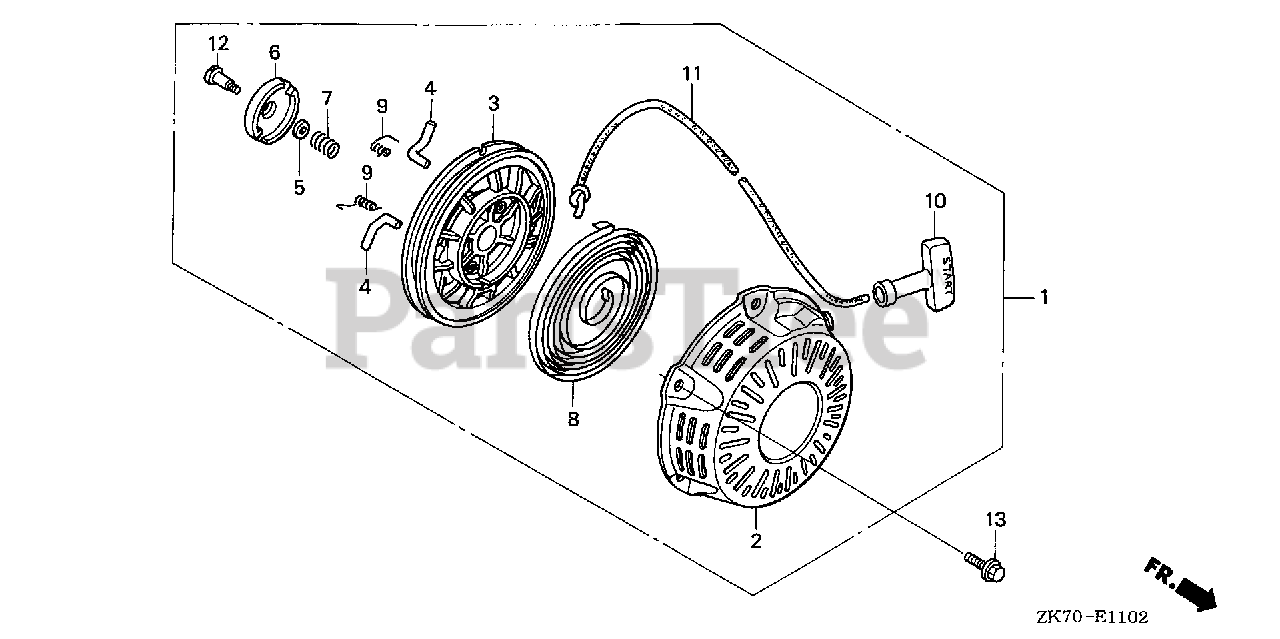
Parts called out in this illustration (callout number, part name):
1	STARTER ASSY., RECOIL *NH105* (MAT BLACK)
2	CASE, RECOIL STARTER *NH105* (MAT BLACK)
3	REEL, RECOIL STARTER (BLACK)
4	RATCHET, STARTER
5	PLATE, FRICTION
6	GUIDE, RATCHET
7	SPRING, FRICTION
8	SPRING, RECOIL STARTER
9	SPRING, RETURN
10	GRIP, STARTER
10	KNOB, RECOIL SRARTER
11	ROPE, RECOIL STARTER
12	SCREW, SETTING
13	BOLT, FLANGE (6X10)
